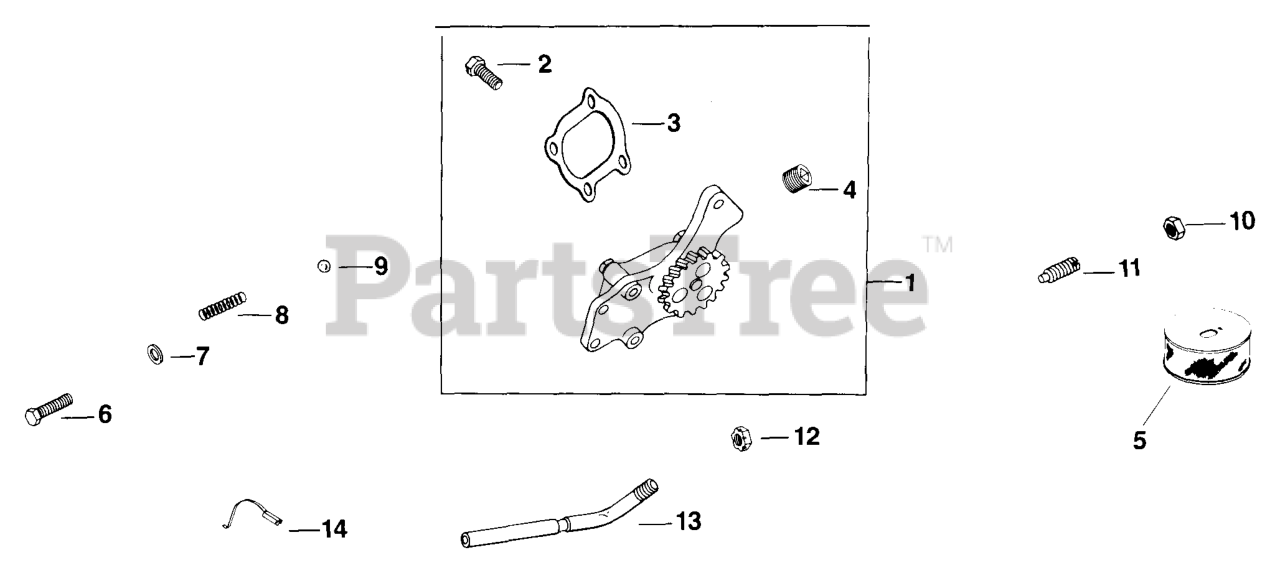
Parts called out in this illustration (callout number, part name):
1	PUMP
3	GASKET, OIL PUMP - DISCONTINUED
4	PLUG, CTSK PIPE 1/8" USE 25 139 60-S
5	STRAINER - DISCONTINUED
10	NUT USE 25 100 14-S
12	NUT-DISCONTINUED
13	TUBE - (#DSC)
